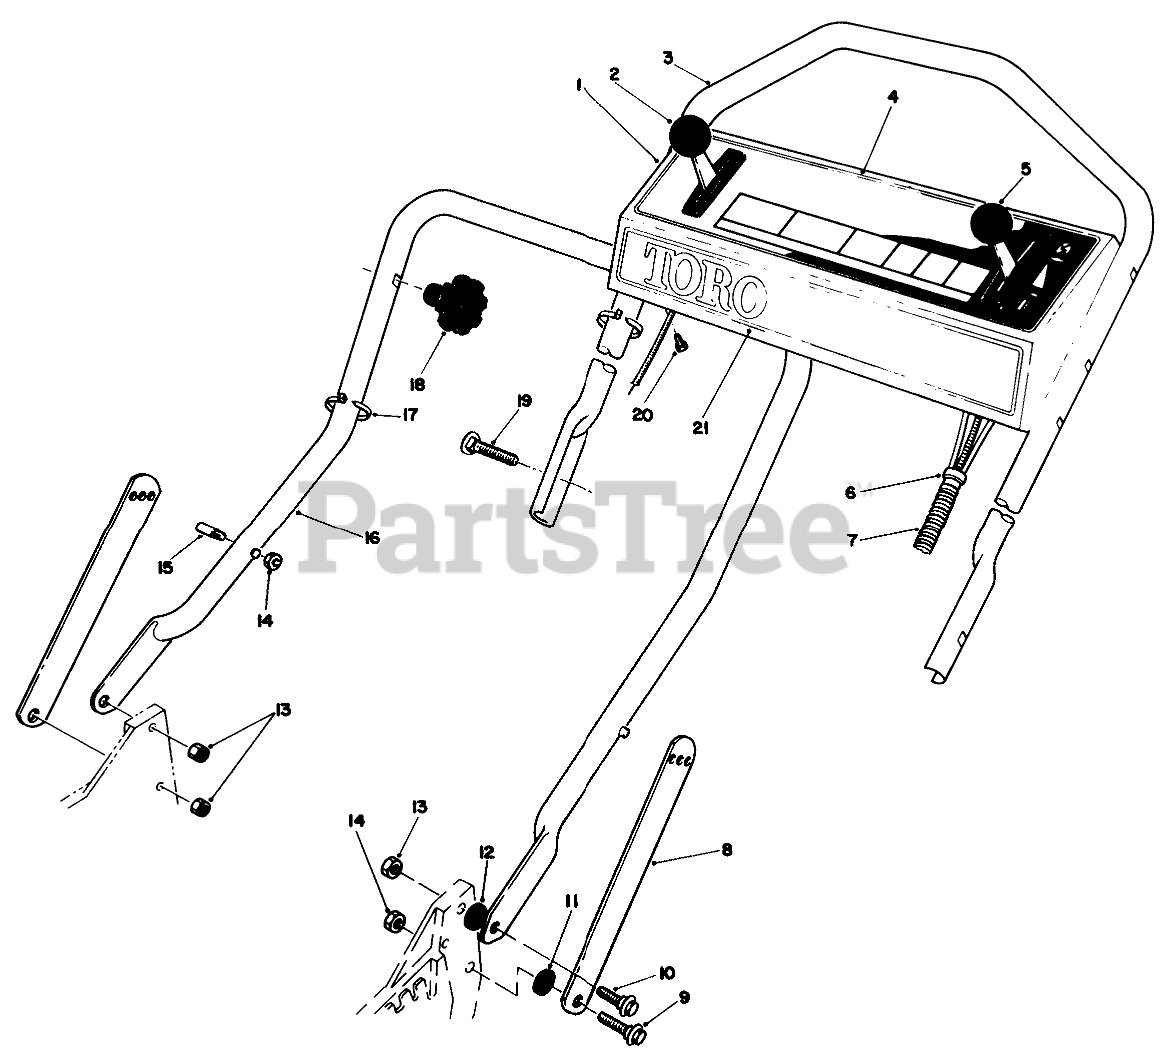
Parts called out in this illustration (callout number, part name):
1	Panel-Control (Incl. Ref. #4)
2	GROUND SPEED CONTROL
3	Handle-Upper
4	Decal-Instruction
5	THROTTLE CONT-SERVICE
6	FITTING-RING
7	CONTROL CABLE COVER
8	Handle Latch
9	SCREW-SHOULDER
10	SCREW-SHOULDER
11	SPACER
12	SPACER
13	NUT-LOCK, NI
14	NUT-LOCK, NI
15	HANDLE PIN
16	LOWER HANDLE ASM
17	TIE-CABLE
19	5/16-18 X 2 HNDLE SCREW
20	SCREW-HWHTF
21	Decal-Toro
